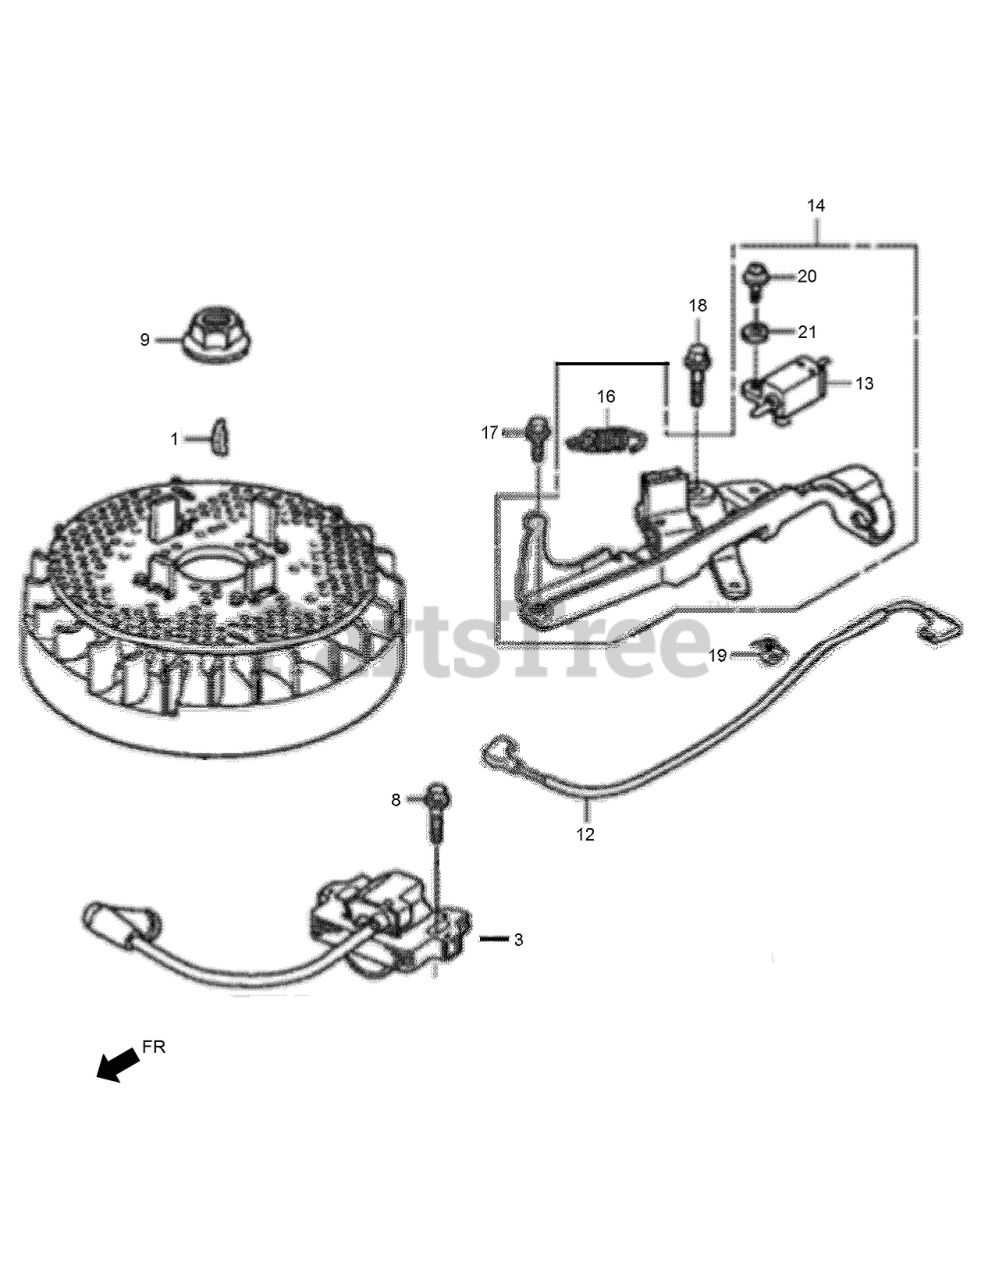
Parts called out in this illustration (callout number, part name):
1	KEY-SPECIAL WOODRUFF-25X18
3	COIL ASM-IGNITION (to S/N 2759741)
3	COIL ASM-IGNITION (from S/N 2759742)
8	BOLT-FLANGE-6X20
9	NUT-SPECIAL-14MM
12	CORD-STOP SWITCH
13	SWITCH ASM-ENGINE STOP
14	BRAKE ASM (from S/N 4287165)
14	BRAKE ASM (to S/N 4287164)
16	SPRING-BRAKE LEVER
17	BOLT-FLANGE-6X14
18	BOLT-FLANGE-6X23
19	CLIP A-CABLE
20	SCREW-WASHER-4X12
21	WASHER-PLAIN-4MM
